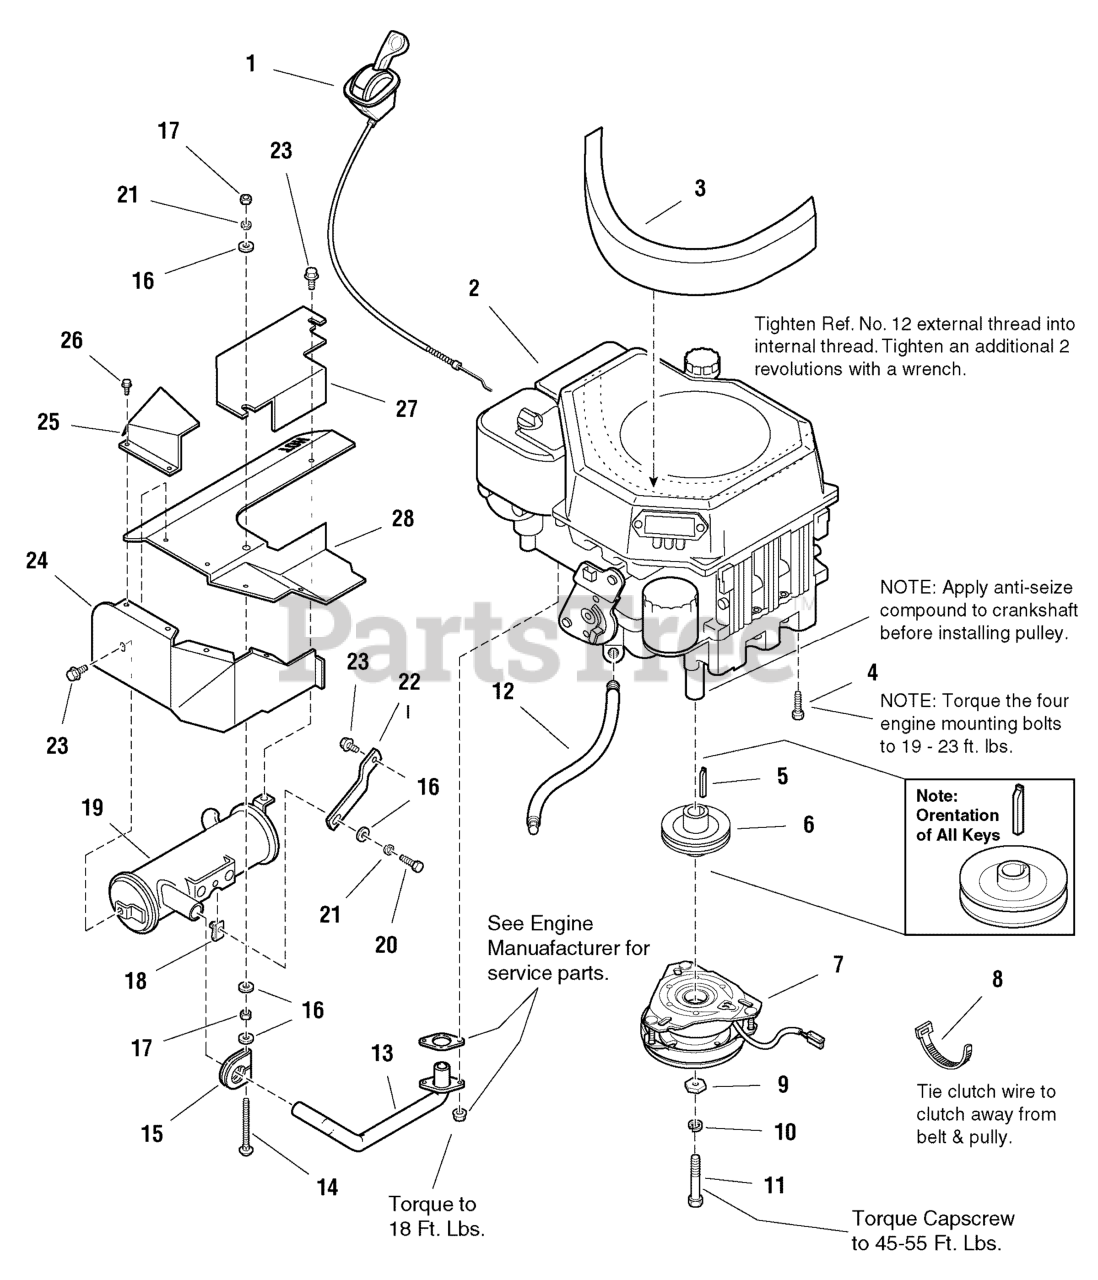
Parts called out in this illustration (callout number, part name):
1	CONTROL, Throttle
2	ENGINE, 18HP, KOHLER
3	SEAL, Foam
4	SCREW, Hex Washer Head Taptite, 3/8-16 x 1
5	KEY, Hi-Pro, 1/4 x 2-1/2
6	PULLEY ASSY, PTO
7	CLUTCH, Electric Ogura
8	TIE, Self Locking, 3-5/8 LG
9	WASHER, Hex
10	LOCKWASHER, Spring, 7/16
11	CAPSCREW, Hex Head, 7/16-20 x 3, G5
12	HOSE, Oil Drain
13	PIPE, Exhaust
14	CARRIAGE BOLT, 5/16-18 x 3-1/4, G5
15	CLAMP, Muffler, 1.312 Dia.
16	WASHER, 5/16
17	NUT, Hex, 5/16-18 NC-2B
18	NUT, Speed, Lug Type, 5/16-18
19	MUFFLER ASSEMBLY
20	CAPSCREW, Hex Head, 5/16-18 x 1
21	WASHER, Lock Helical Spring
22	SUPPORT, Muffler
23	SCREW, Hex Washer Head, Taptite, 5/16-18 x 1/2
24	DUCT, Air, Bottom
25	SHIELD, Heat
26	CAPSCREW, Thread Cutting, # 10 x 1/2
27	SHIELD, Muffler, Oil Filter Access Panel
28	SHIELD, Muffler
